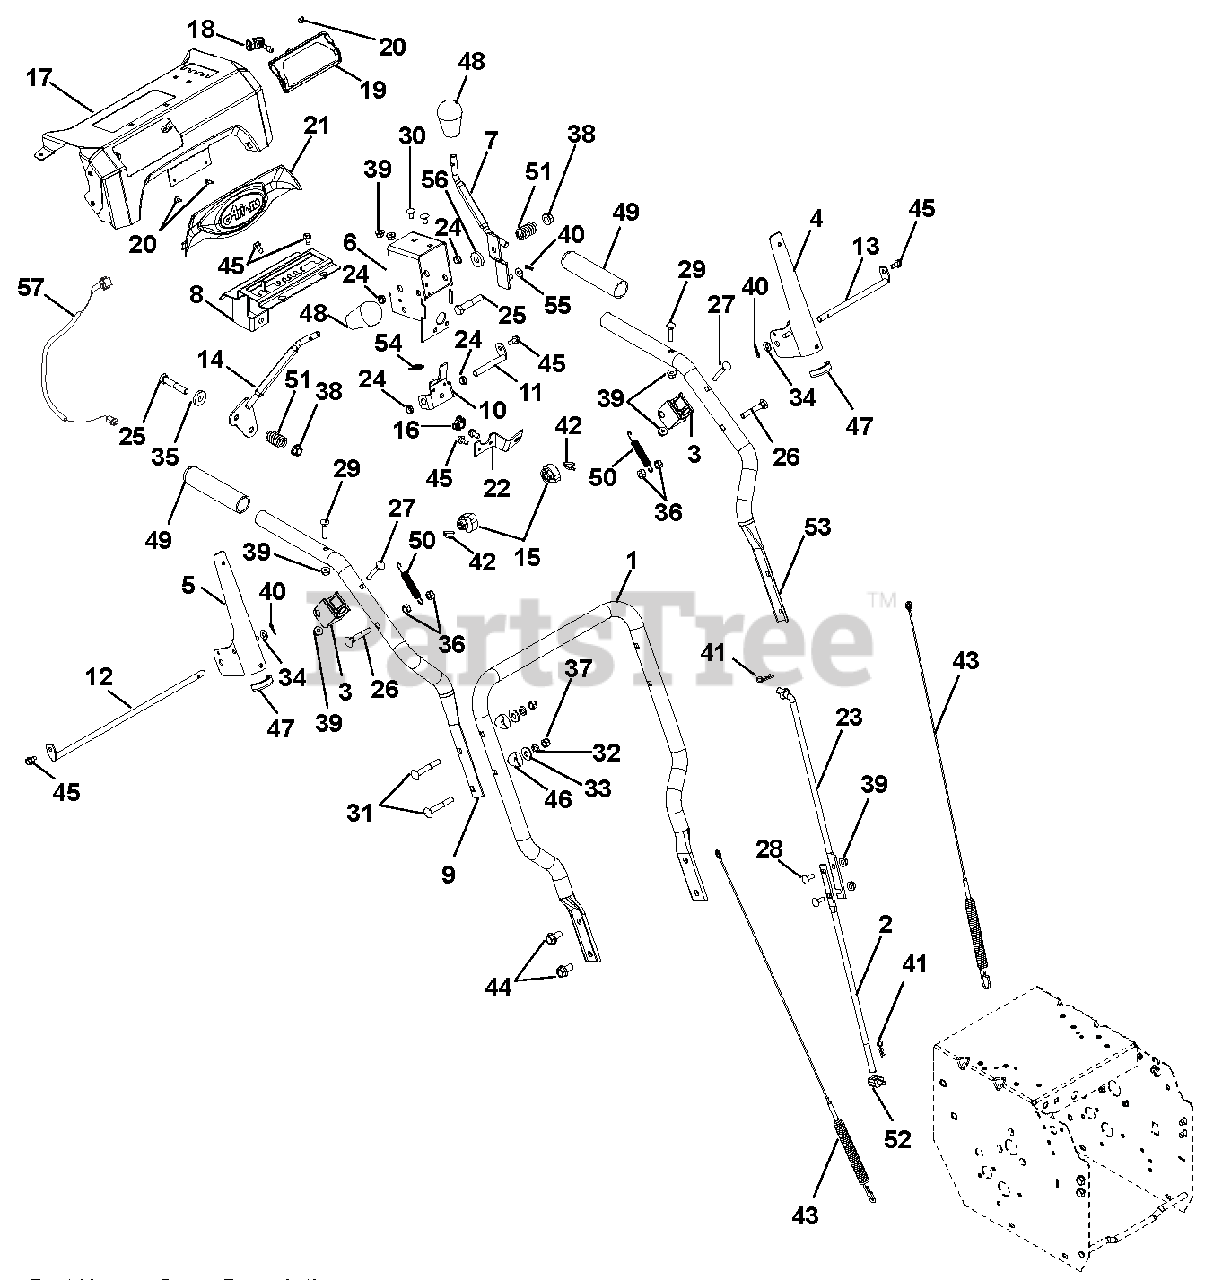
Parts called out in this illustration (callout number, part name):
1	HANDLEBAR, LOWER (COMPACT)
2	ROD, SHIFT - LOWER
3	BLOCK, CLUTCH PADDLE
4	LEVER, CLUTCH-LH
5	LEVER, CLUTCH-RH
6	WELDMENT, BRACKET INTERLOCK
7	WELDMENT, CONTROL LEVER (DEFL)
8	WELDMENT, DETENT PLATE-COMPACT
9	HANDLEBAR, UPPER - RH
10	BRACKET, INTERLOCK ARM
11	ROD, PIVOT - INTERLOCK
12	ROD, PADDLE MOUNT - LONG
13	ROD, PADDLE MOUNT - SHORT
14	LEVER, CONTROL-SHIFT(WELDMENT)
15	CAM, INTERLOCK
16	CRANK BUSHING, NYLON CHUTE BK
17	CONTROL PANEL W/DECAL, ARIENS
17	CTRL PANEL W/DECAL, ARIENS REM
18	BULB, LIGHT-HALOGEN 20W
19	HEADLIGHT ASSY, HALOGEN 20W
20	SCR-TAP #10X.50 BOSS INDHXHD
21	DASH BEZEL, ARIENS LOGO - COMP
22	ANCHOR, DEFLECTOR CABLE
23	ROD, SHIFT - UPPER
24	BUSHING, POLYLINER-.38 SNAPIN
25	@BLT-HEX .38-16X2.00 GR5 YWZC
26	BLT-RDHDXLSQNK .31-18X2.0 G5YZ
27	BLT-RDHDXLSQNK .25-20X2.0 G5YZ
28	@BLT-RDHDSQNK .25-20X.75 G5YZ
29	BLT-RDHDXLSQNK.25-20X1.25 G5ZC
30	@BLT-RDHDSQNK .25-20X.50 G5YZ
31	@BLT-RDHDSQNK .31-18X2.25 G5YZ
32	WSHR-LK .312X.097 HVY YWZC
33	@WSHR-FL-STL.38X.875X.083 YWZC
34	@WSHR-FL-STL.281X.62X.065 YWZC
35	WSHR-FL-STL .406X1.00X.188 YWZ
36	@NUT-LK-CTR .31-18 YWZC
37	@NUT-LK-NYL .312-18 YWZC
38	@NUT-LK-TOP-FLG .38-16 YWZC
39	@NUT-LK-TOP-FLG .25-20 YWZC
40	PIN-HAIR INT .06X.18X.77
41	PIN-HAIR INT .08X.18X1.18 YWZC
42	PIN, SPRING CLIP
43	CABLE, AUGER & UPPER TRACTION
44	BLT-SERHFWH .38-16X.75 YWZC
45	SCR-TAP .25-20X.50 HWH TR YWZ
46	SPACER, HANDLEBAR
47	EDGING, CLUTCH PADDLE - 2.00"
48	KNOB,SOFT TEARDROP,PUSH-ON GRY
49	HANDLE GRIP
50	SPRING, EXTENSION
51	SG-COMP .125X.781X1.250
52	PIVOT,SHIFT ROD .375-16(TRUNN)
53	HANDLEBAR, UPPER - LH
54	SPRING-EXT .047X.438X1.45
55	BSHG-SLV .265X.500X.219
56	WSHR-FL-STL .380X1.50X.062 YWZ
57	HARNESS, LIGHT - COMPACT
